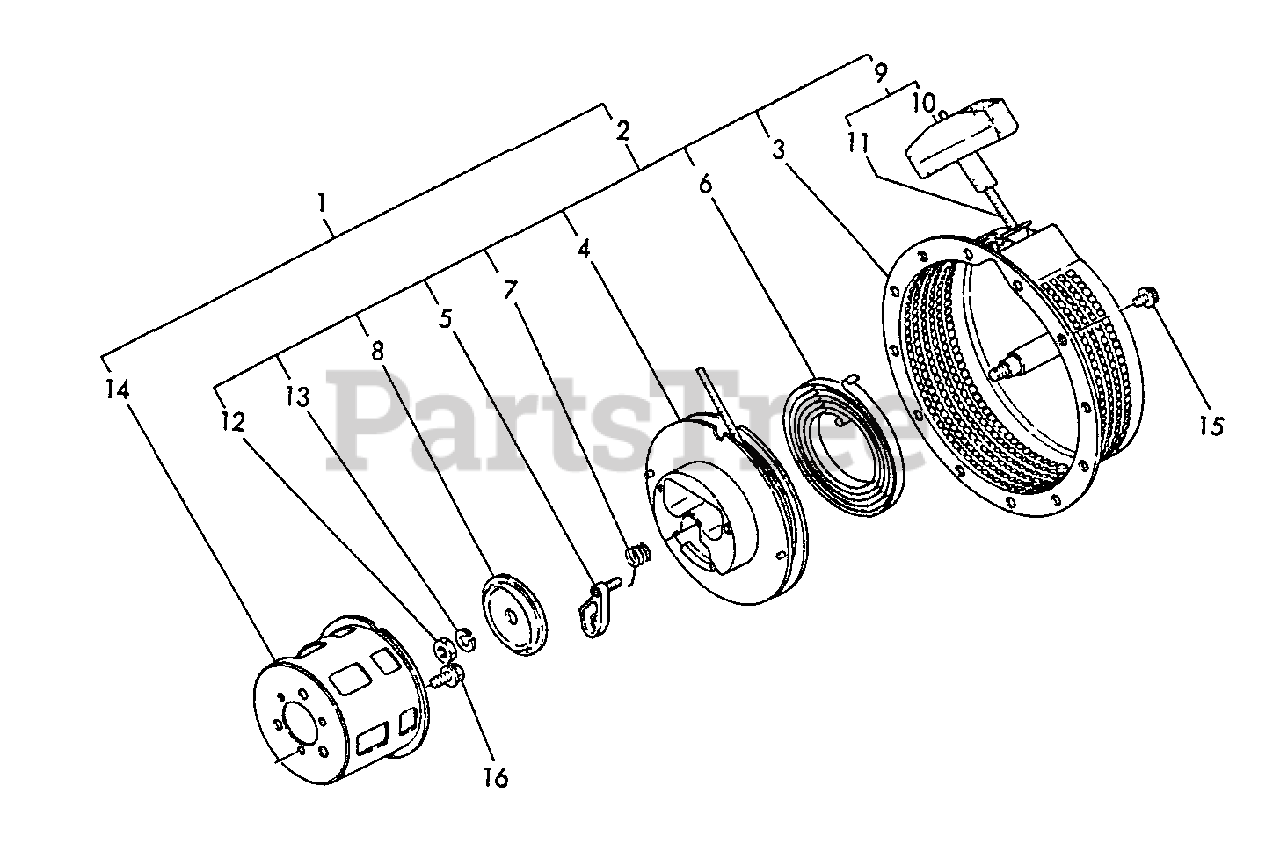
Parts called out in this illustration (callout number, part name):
1	STARTER ASSY
2	STARTER ASSY
3	CASE, STARTER
4	PULLEY
5	RATCHET
7	SPRING, FRICTION
8	PLATE, FRICTION
9	ROPE ASSY
10	GRIP, STARTER
11	ROPE, STARTER
12	NUT
13	LOCKWASHER
14	PULLEY, STARTER
15	BOLT - 6X8 -- PLATED
16	BOLT - 6X12 -- PLATED
